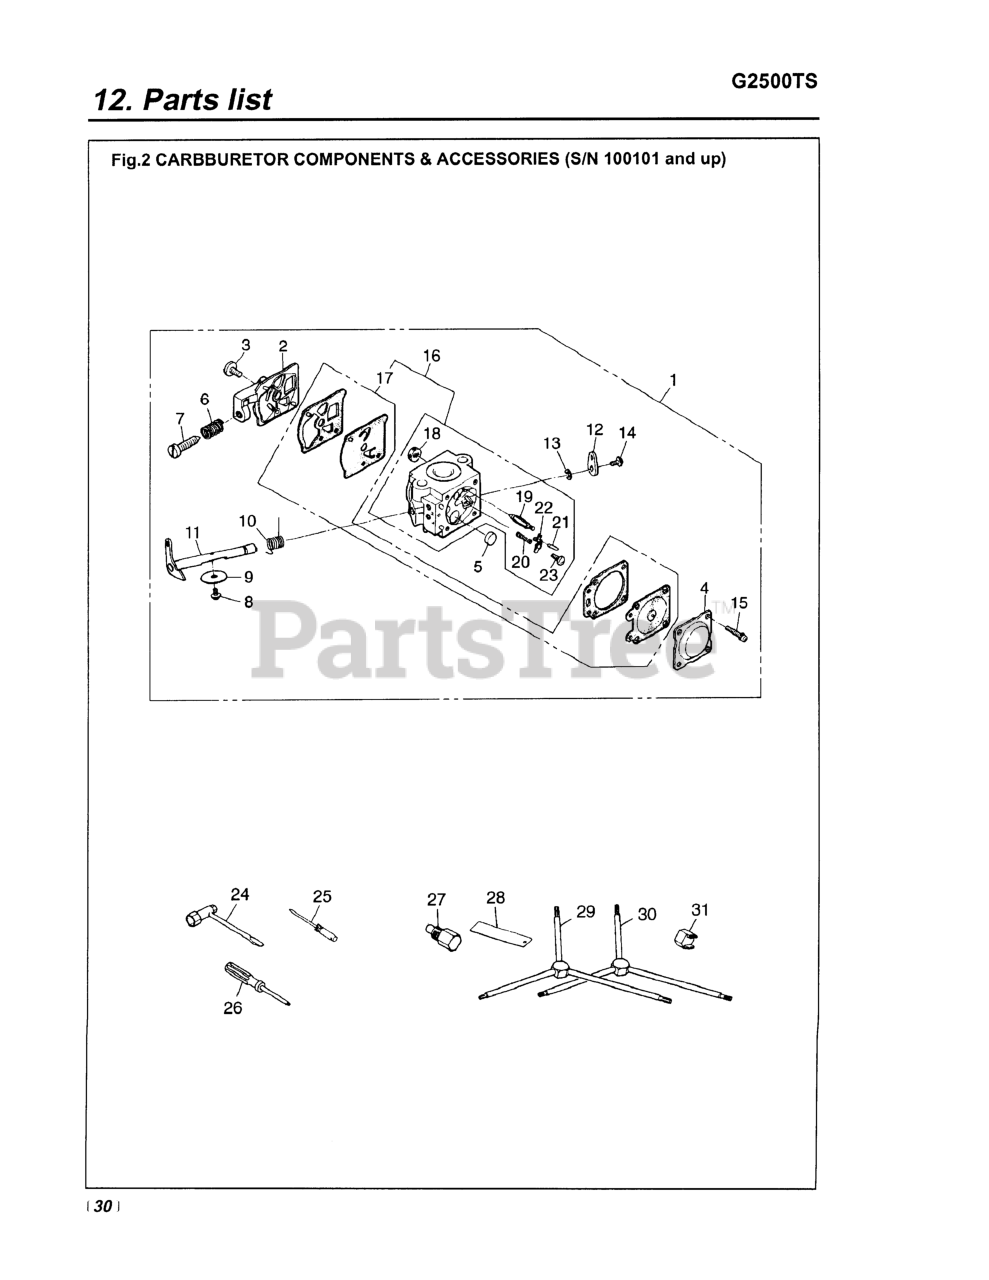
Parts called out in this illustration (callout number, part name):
1	CARBURETOR
5	PLUG, WELSH
6	SPRING, IDLE
8	SCREW (RPLS 3310-81360)
10	SPRING, RETURN
11	SHAFT ASSEMBLY
15	SCREW ASSEMBLY
16	KIT, REBUILD
18	SCREEN
19	VALVE, INLET
21	PIN
22	LEVER
23	SCREW
24	WRENCH, PLUG
25	SCREWDRIVER
26	SCREWDRIVER
27	STOPPER (TOOL) (RPLS 3320-9641
28	GUAGE, AIR GAP (TOOL)
29	HEX WRENCH (TOOL)
31	WRENCH
